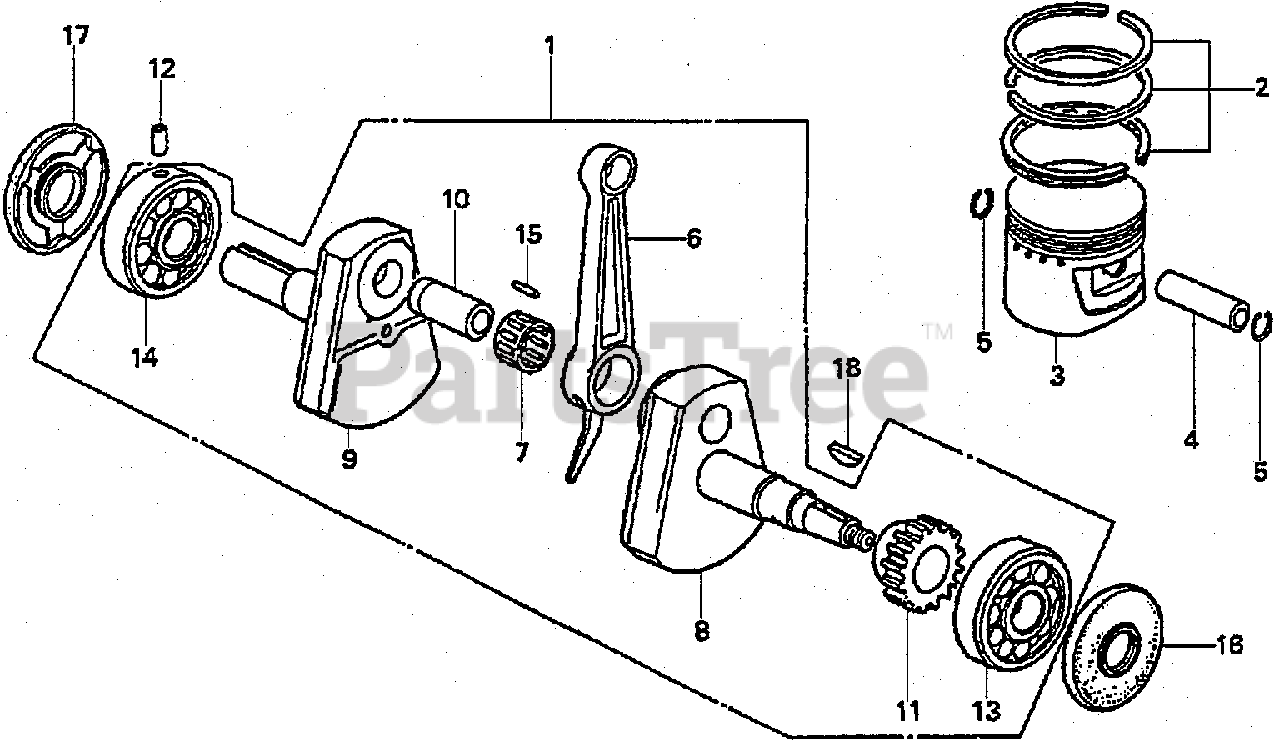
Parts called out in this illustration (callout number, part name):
1	CRANKSHAFT
2	RING SET, PISTON (STD) (NOT AVAILABLE)
2	RING SET, PISTON (OS 0.25)
2	RING SET, PISTON (OS 0.50)
2	RING SET, PISTON (0.75)
3	PISTON (STD) (NOT AVAILABLE)
3	PISTON (OS 0.25)
3	PISTON (OS 0.50)
3	PISTON (0.75)
4	PIN, PISTON
5	CLIP, PISTON PIN (19MM)
6	ROD, CONNECTING (NOT AVAILABLE)
7	RETAINER, ROLLER
8	CRANKSHAFT, R.
9	CRANKSHAFT, L.
10	PIN, CRANK (N/A: SEE ASSEMBLY)
11	GEAR, TIMING
12	PIN, KNOCK (7X12) (NOT AVAILABLE)
13	BEARING, RADIAL BALL (6306S)
14	BEARING, SPECIAL BALL (6306S6HS) (NOT AVAILABLE)
15	ROLLER, ROD (3X16)
16	OIL SEAL (30759) (NOT AVAILABLE)
16	OIL SEAL (PJ30759)
17	OIL SEAL (PJ30779)
18	KEY, SPECIAL WOODRUFF (25X18)
